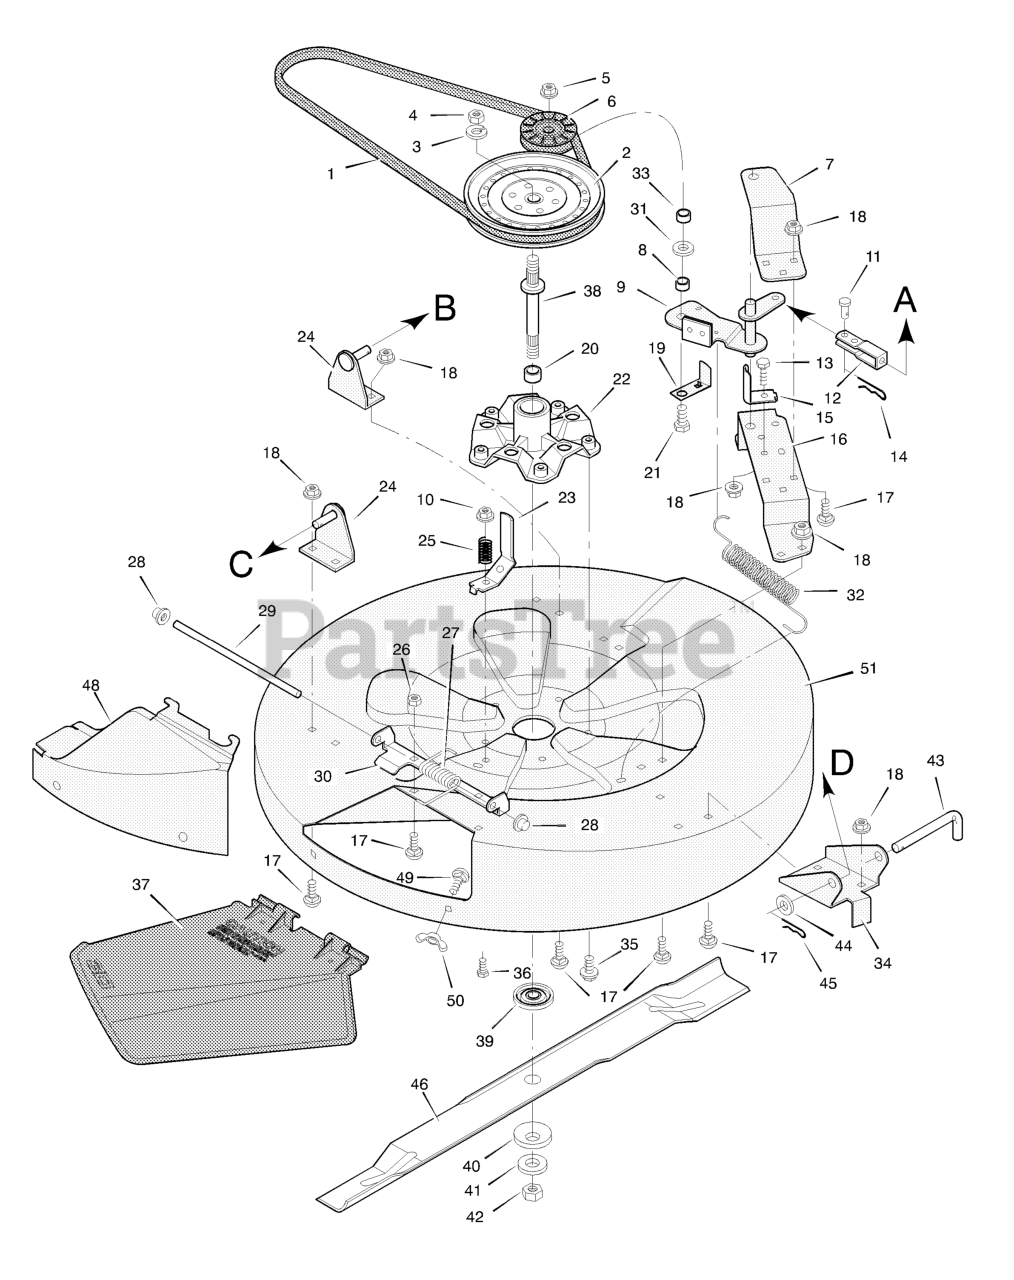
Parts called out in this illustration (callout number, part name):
1	Belt, Mower Drive
2	Pulley, Splined
3	Lockwasher
4	Locknut, Hex
5	Nut, Hex
6	Pulley, Idler
7	Bracket, Upper Idler
9	Assembly, Blade Idler
10	Locknut, Flange
11	Pin, Clevis
13	Bolt, Hex
14	Pin, Hair
15	Guide, Belt
16	Bracket, Lower Idler
17	Bolt, Carriage
18	Nut, Flange
19	Guide, Belt
21	Bolt, Hex
22	Housing, Mandrel
23	Guide, Belt
24	Bracket, Hanger
25	Spring, Compression
26	Nut, Hex
27	Spring - Torsional
28	Push On Cap
30	Hinge, Chute Deflector
32	Spring, Extension
34	Bracket, Front
36	Bolt, Hex
37	Deflector, Chute
38	Mandrel
39	Adapter, Blade
40	Washer, Belleville
41	Washer, Hardened
42	Nut, Hex
43	Pin, Pull
45	Pin, Hair
46	Blade, Mulching
48	Plate, Mulcher
49	Bolt, Carriage
50	Wingnut
